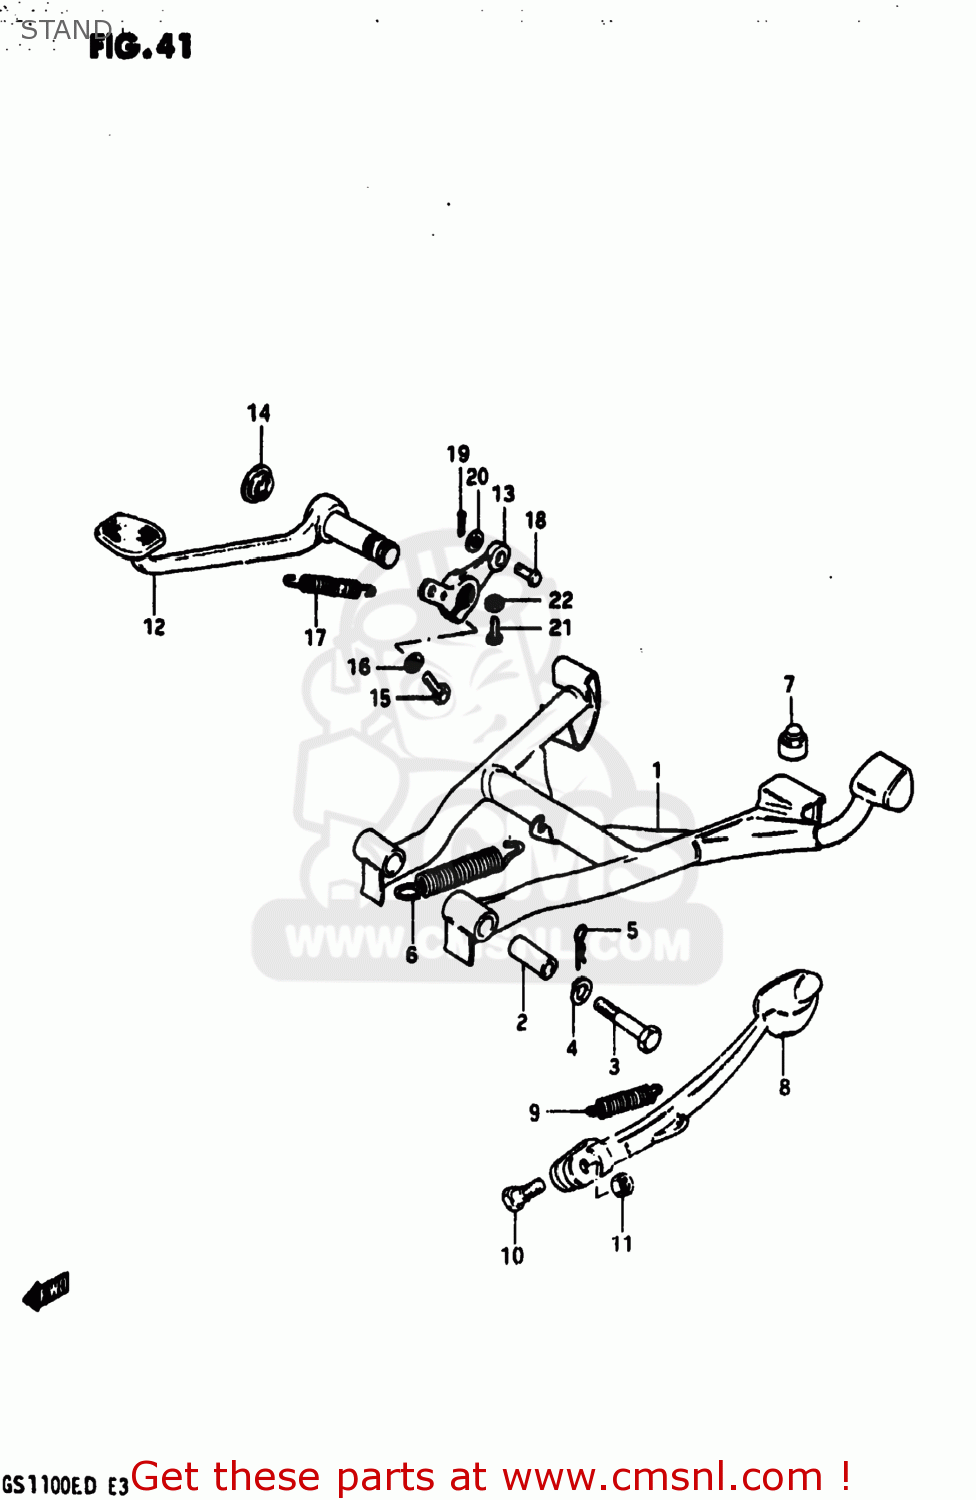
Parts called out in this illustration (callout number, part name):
1	STAND,CENTER
2	SPACER(10X16X38.8)
3	BOLT
4	LOCK WASHER
5	CLIP
6	SPRING
7	CUSHION
8	STAND,SIDE
9	SPRING
10	BOLT(10X30)
11	NUT
12	PEDAL,BRAKE
13	ARM,BRAKE PEDAL
14	CAP, BRAKE PEDAL
15	BOLT
16	LOCK WASHER
17	SPRING
18	PIN
19	PIN
20	WASHER
21	BOLT
22	NUT
